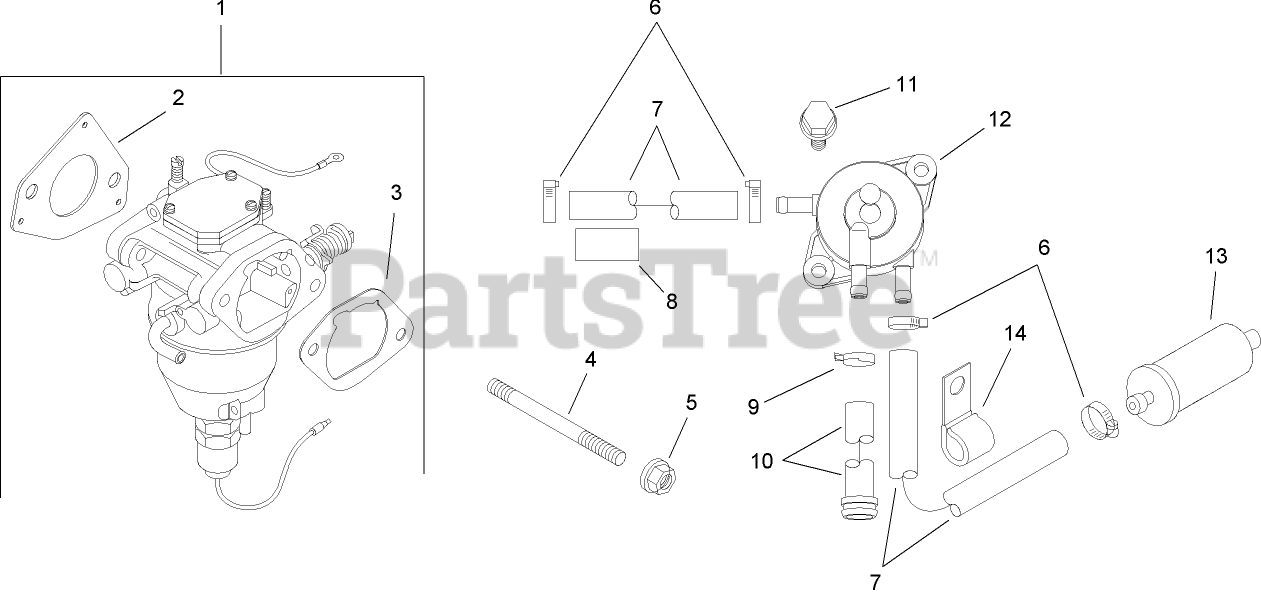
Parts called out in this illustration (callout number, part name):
1	Carburetor Kit w/Gaskets (Includes 2-3)
2	GASKET-CARBURETOR
3	GASKET-BASE, AIR CLEANER
4	STUD (M6X1.0X106)
5	NUT-FLANGE (M6X1.0)
6	CLAMP-HOSE, SPRING (1/2)
7	LINE-FUEL (24-CUT TO LENGTH)
8	SLEEVE-ABRASION, ANTI
9	CLAMP-HOSE
10	HOSE-FUEL PUMP W/CLAMP (INCLUDES 10)
11	SCREW-TAP (M6X1.7X18)
12	PUMP-FUEL
13	FILTER-FUEL
14	CLIP-CABLE
15	CHOKE REPAIR/SERVICE KIT
16	GASKET REPAIR/SERVICE KIT
17	FLOAT REPAIR KIT
18	SOLENOID VALVE REPAIR KIT
19	Overhaul Kit w/Gaskets
20	Overhaul w/gaskets Kit
21	Choke Service Repair Kit
22	Gasket Service Repair Kit
23	Solenoid Valve Service w/Gaskets Kit
